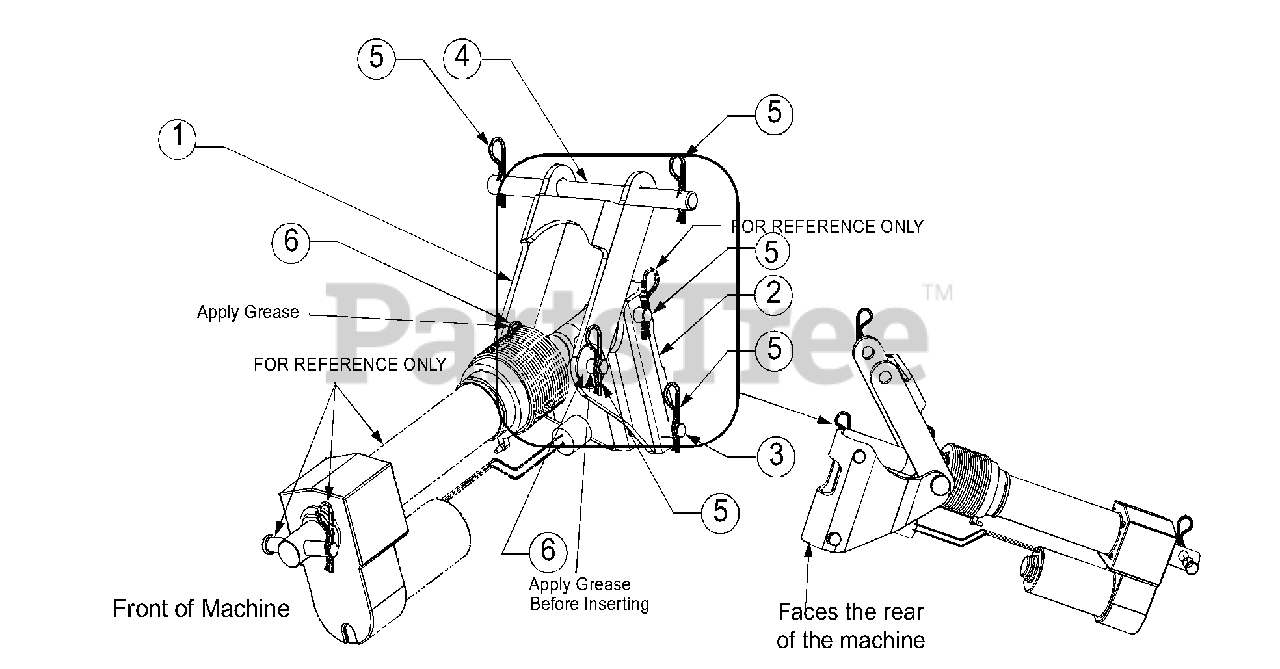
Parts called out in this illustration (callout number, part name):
4	Rod, Mount .625 x 8.625
5	Internal Cotter Pin
6	Flat Washer,.51 ID x 1.5 OD x.07
